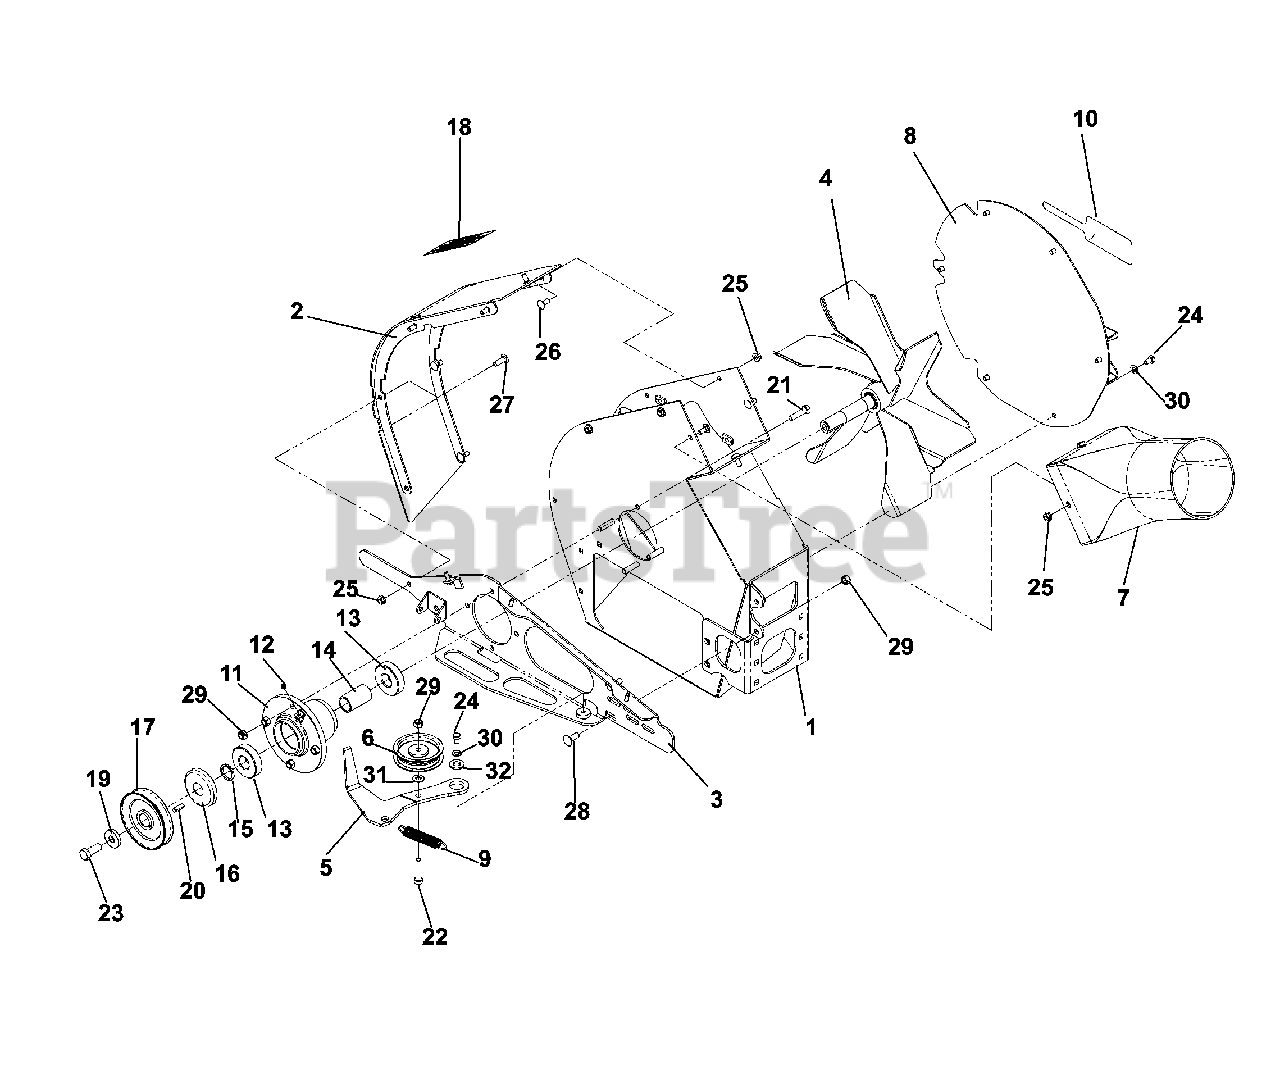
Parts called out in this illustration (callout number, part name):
1	HOUSING WLDT
2	SANDLINER WLDT.
3	HUB PLATE
4	FAN WLDT.
5	IDLER ARM
6	PULLEY, IDLER 3 METAL
7	BLOWER EXIT TUBE
8	OUTER PLT WLDT
10	DECAL, DIXON
11	DECK HUB MACHINED
12	ZERK, 3/16, DRIVE IN
13	BEARING - 6305 - 2RS
15	HUB PULLEY SPACER
16	TRASH GUARD
18	G.C.WARNING DECAL
19	WASHER .525 X 1.375 X .25
20	KEY - 1/4 X .88
21	HCS 3/8C X 1 1/2
22	HCS 3/8-16 X 1 3/4 GR5
23	1/2-20 UNF X 1 1/4 HHBLT
24	5/16-18X1/2 HHB GR5
25	5/16-18 FLANGED L-NUT
26	BOLT 5/16C X 3/4" CARRIAGE
27	RHSSNB 5/16C X 1.0
28	RHSNB 3/8C X 1
29	NUT 3/8-16 NYLOC
30	FLAT WASHER 5/16 SAE
31	WASHER 3/8 SAE FLAT
32	WASHER 1/2" FLAT
